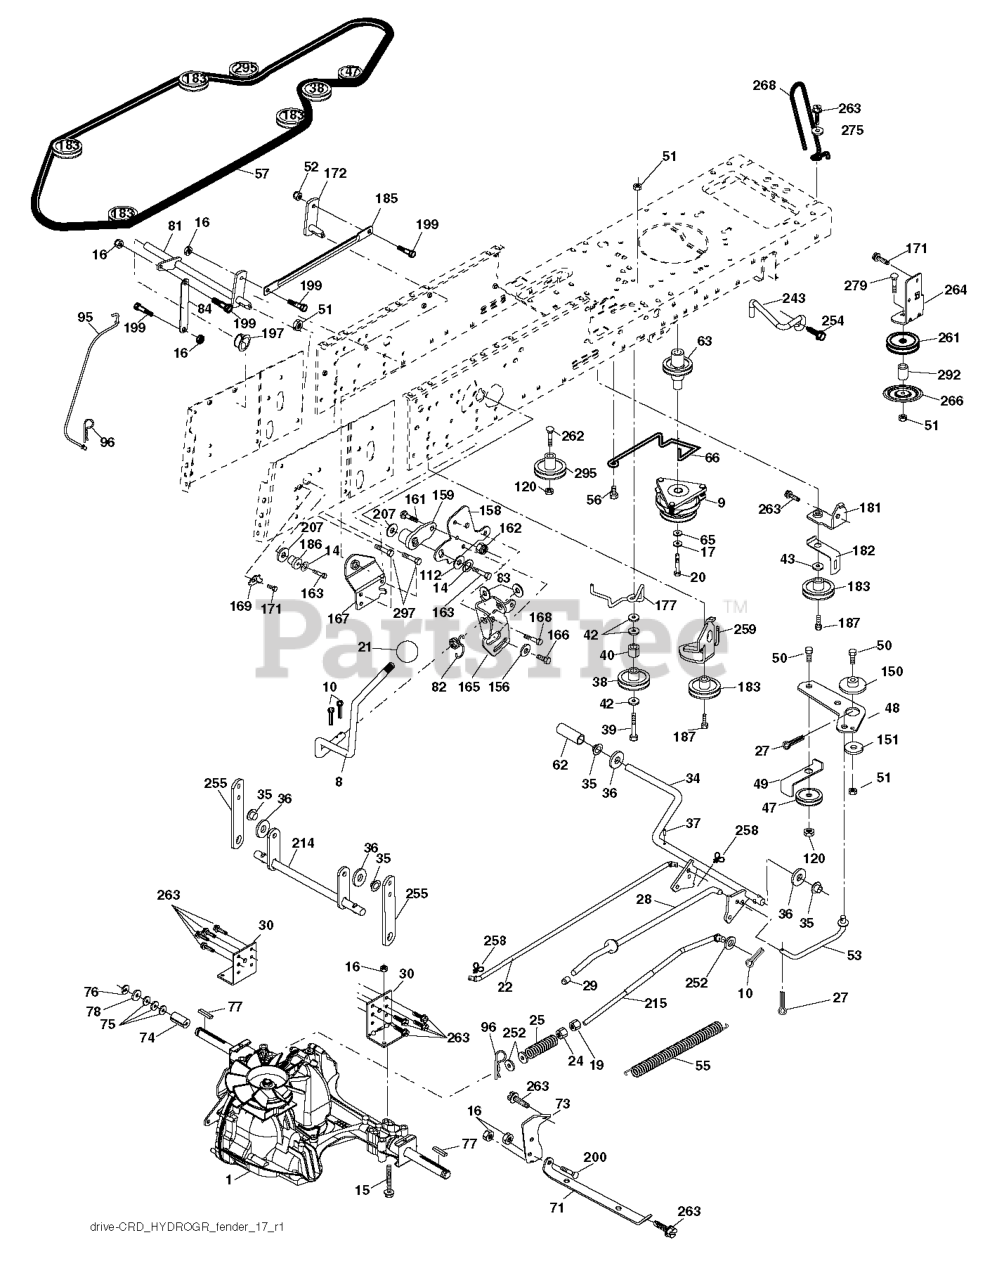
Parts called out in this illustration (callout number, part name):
8	ROD SHIFT FENDER ADJUST LT
9	CLUTCH.ELECTRIC.OGURA.EURO.
10	PIN COTTER
14	LOCKWASHER
15	BOLT HEX 5/16-18 GR 5
16	NUT.71038.31-18.HEX.NYLOCK
19	NUT
20	BOLT HEX 7/16-20X4-1/4"
21	KNOB.DUCKHEAD.1/2
22	ROD
24	NUT
25	SPRING BRAKE ROD
27	COTTER PIN
28	ROD, PARKING BRAKE
29	CAP
30	BRKT, TRNSXLE MNT 20"
34	SHAFT, FOOT PEDAL
35	BEARING.NYLON
37	DRIVE PIN
38	PULLEY.FLAT
42	WASHER
47	IDLER PULLEY
48	BELLCRANK, CLUTCH
49	RETAIN BELT
50	BOLT.3/8-16X1.50
52	LOCKNUT
53	LINK.CLUTCH.7.66.2005
55	SPRING, RETURN LT
56	SCREW.3/8-16
57	V-BELT 113"
62	PEDAL COVER T
63	PULLEY.ENGINE.CVX.LT
65	LOCKWASHER
66	KEEPER BELT ENGINE
71	STRAP TORQUE LH HYDRO
73	STRAP TORQUE RH HYDRO
74	SPACER AXLE
77	SQUARE KEY
81	ASM.CROSS.SHAFT.REAR.CRD.0510
82	SHIFT SPRING
83	WASHER
84	LINK.PNT.TRANSAXLE.0510.CRD
95	LINK
96	RETAINER M
120	NUT LOCK FLG 3/8-16 UNC
150	BUSHING.BELLCRANK.GRD.DR
151	WASHER 12/32X2X10GA
156	WASHER.SRRTD.5/16
158	BRACKET
159	RB HUB.SHIFT
161	BOLT
162	NUT.CROWNLOCK.1/4
165	RP BRACKET
166	CAPSCREW.HXHD.FLG.5/16-18X.625
167	BRACKET.SUPT.SHIFT.CRD
168	BOLT.SHOULDER.5/16-18X
169	PLATE.FASTENING.CROSS.SHAFT
172	LINK
181	BRACKET
182	BELT GUIDE
183	PULLEY.V-IDLER.
185	LINK
186	HUB.TAPERED.ROUND.CRD
187	BOLT.5/16-18X1.25
197	NYLINER SNAP 5/8" ID
199	BOLT SHOULDER 5/16-18 UNC
207	WASHER NYL
214	LEVER
215	ROD
243	BRACKET, ANTI-ROTATION
252	WASHER
254	SCREW 3/8-16X1
255	SHAFT
258	CLIP RETAINER
259	BRACKET
261	FLAT IDLER PULLEY
263	SCREW, 3/8-16X3/4
264	BRACKET.IDLER
266	PROTECTOR
268	GUARD MUFFLER
275	WASHER
292	SPACER
295	PULLEY IDLER COMPOSITE
297	SCREW LT.3/8-46X5/8
